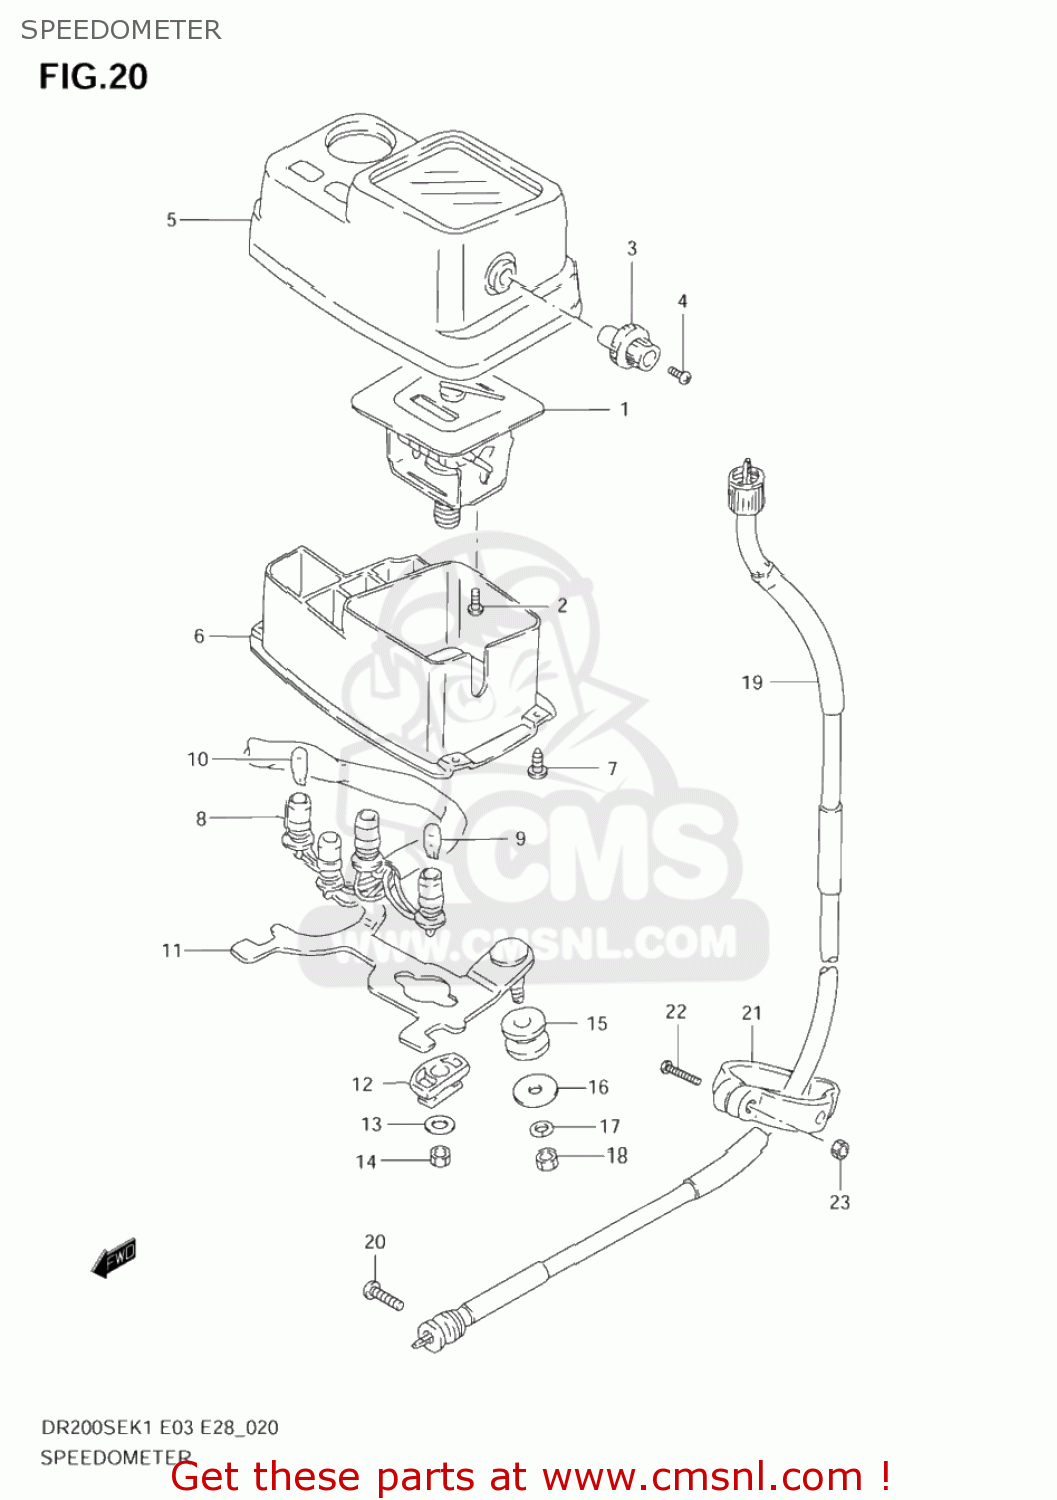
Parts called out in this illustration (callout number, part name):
1	SPEEDOMETER
2	SCREW
3	KNOB,TRIP
4	SCREW(2X6)
5	HOOD,METER
6	CASE,METER
7	SCREW
8	SOCKET ASSY
9	BULB(12V3.4W,T10)
10	BULB(12V1.7W,T10,WB121)
11	BRACKET,METER
12	CUSHION
13	WASHER(5.5X16X1.2)
14	NUT
15	CUSHION
16	WASHER(6.5X18X1.6)
17	LOCK WASHER
18	NUT 6MM
19	CABLE ASSY,SPEEDOMETER
20	SCREW
21	CLAMP,SPEEDOMETER CABLE
22	SCREW
23	NUT
